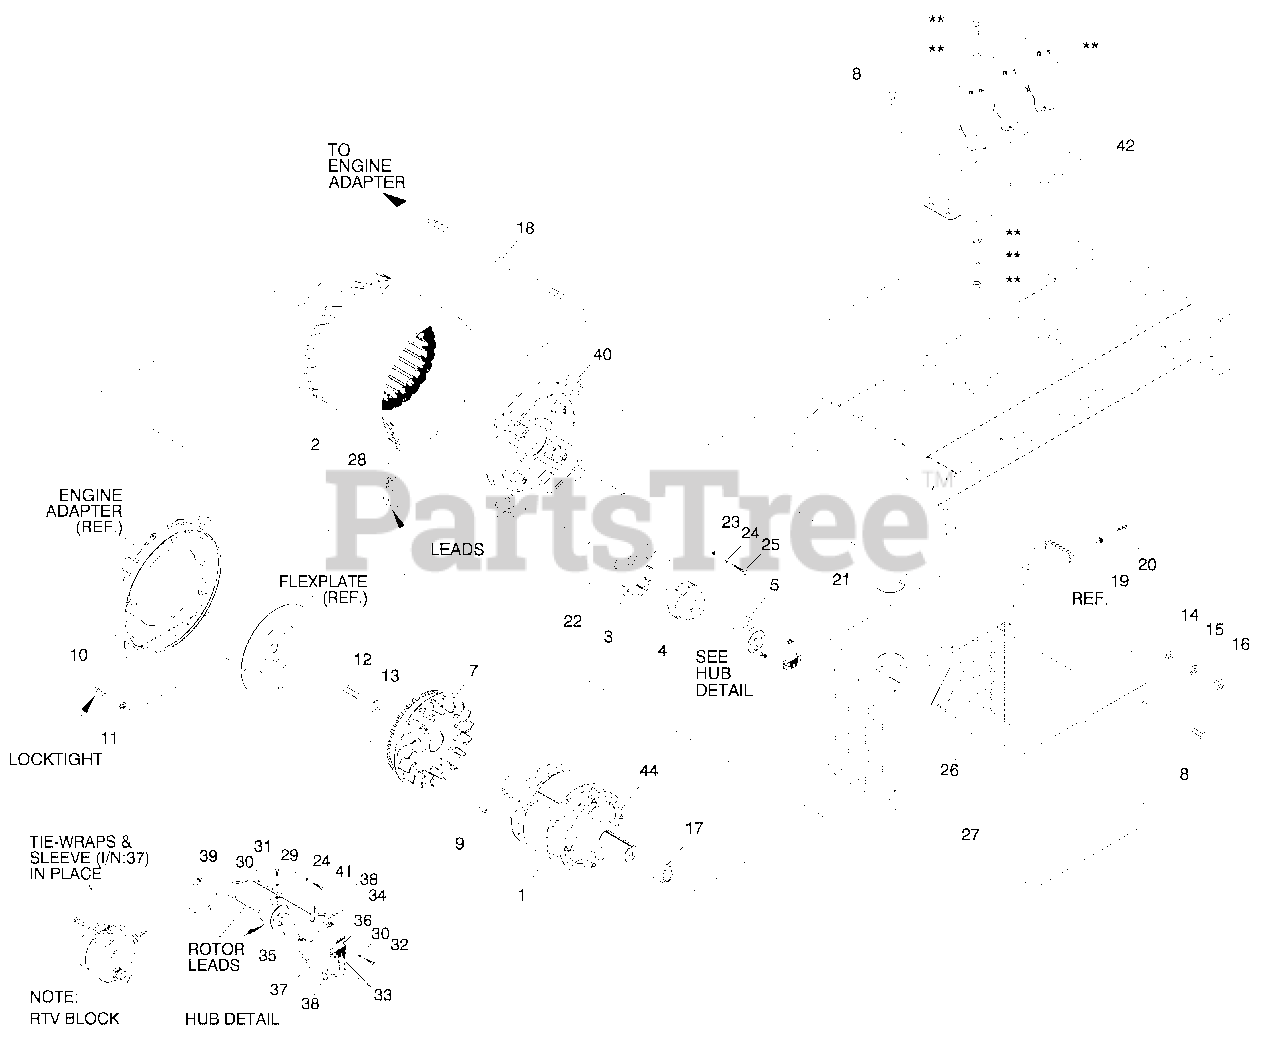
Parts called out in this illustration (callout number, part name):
1	ROTOR 390 70AB3 CPL
2	STATOR 390 70AB3 CPL
3	EXITER FIELD 2"LG SPD CONN
4	ASSY EXCITER 2 .00" STK
5	KEY SQ 3/8 X 3-1/4 STEEL
7	ASSY FLYWHEEL CPL
8	SCREW THF M6-1 X 16 N WA Z/JS
9	KEY WOODRUFF #E
10	SCREW HHC M10-1.50 X 16 G10 .9
11	WASHER LOCK M10
12	SCREW HHC M16-2. 0X45G8 .8
13	SPACER .69 X 2.75 X .37 ST/ZNC
14	WASHER FLAT M14
15	WASHER LOCK M14
16	NUT HEX M14-2.0G8YEL CHR
17	COLLAR SLIP FIT 390 MM
18	STUDM14-2.0X650 G5ZINC
19	WASHER LOCK #6
20	SCREW PHTT #6-32 X 1/2 ZYC
21	BUSHING SNAP SB-2 .5-31
22	PIN DOWEL 1/2 X 1-1/4
23	WASHER FLAT M12
24	WASHER LOCK M12
25	SCREW HHC M12-1.75 X 80 G10 .9
26	SHIELD ALT EXCITER 390
27	COVER EXCITER SHIELD
28	SLEEVE RUBBER
29	CLAMP VINYL .312 X .203 Z
30	WASHER SHAKEPROOF INT #8
31	SCREW HHM #8-32X3/8
32	SCREW HHM #8-32X7/8
33	LUG RT-ANG #10/10-12
34	BRIDGE SUPPORT DIODE 15"
35	CAP END ROTOR 390MM
36	ASSY BRIDGE RECTIFIER
37	SLEEVING UL #0 .330 ID (3" LG)
38	TIE WRAP UL 3 .9 "X . 10" BLK
39	TIE WRAP UL 17 . 7X.35 BLK HT
40	REAR BEARING CARRIER
41	SCREW HHC M12-1.75 X 60 G10 .9
42	MOUNT CT'S 5. 4 L& 6 . 8L
43	BUSHING SNAP SB-2 .5-31
44	BEARING BALL 6212 SEALED
